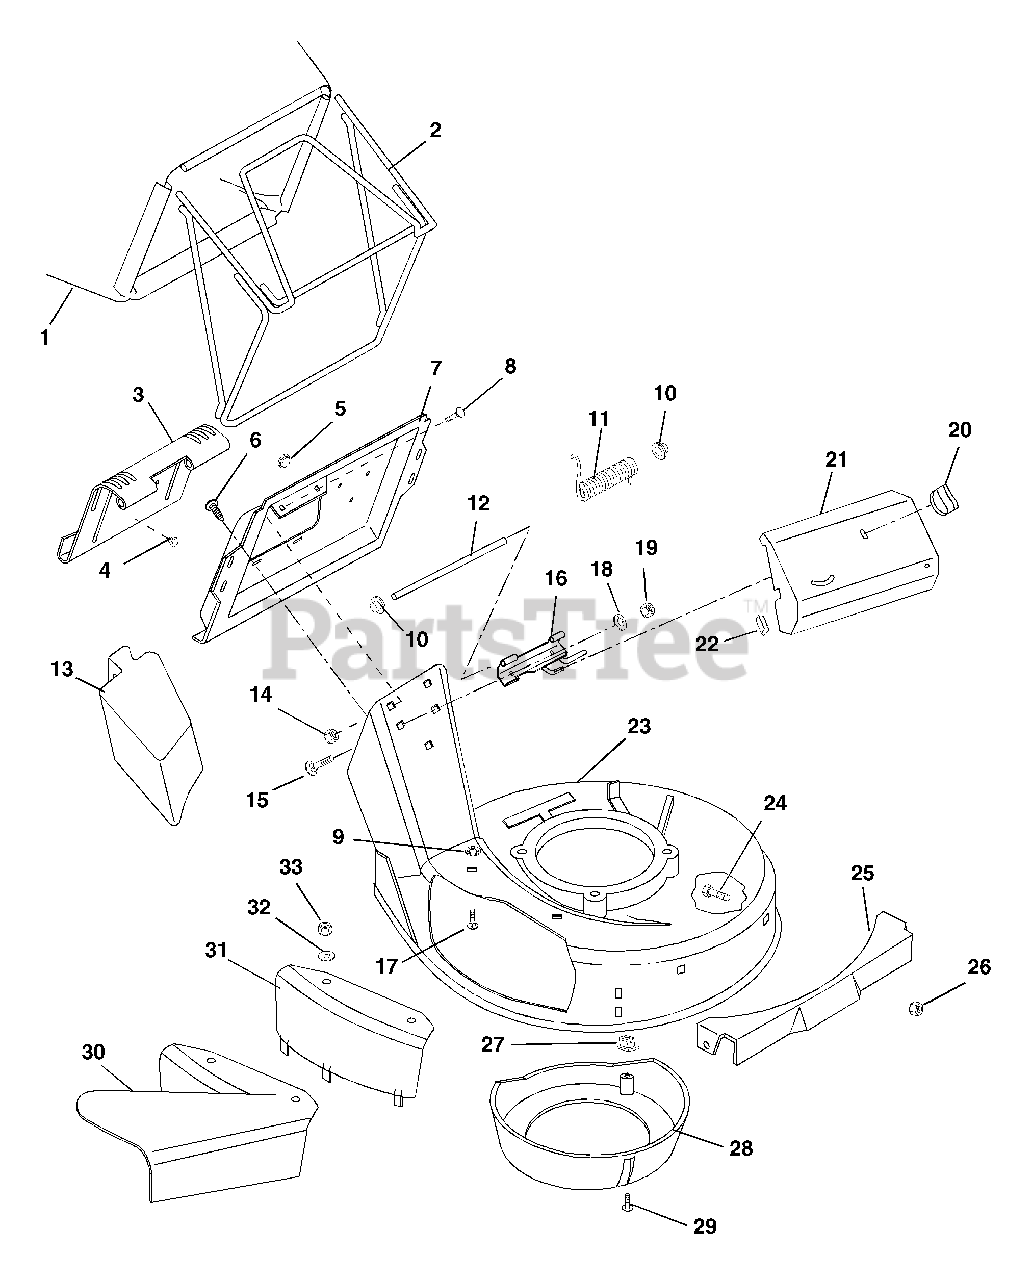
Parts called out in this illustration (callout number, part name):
1	Bag-Consumer Black
2	Bagger Frame
3	Door-Catcher Plate
4	Button Bumper
6	Screw-Tapping 10-24 x .38 Pan Head
7	Plate , Catcher
8	Bolt-Round Head Square Neck .25-20 x .38
9	Nut-Push .312
10	Nut-Push
11	Spring-Torsion .120 x .68 x 3.09
12	Pin-Door
13	Mulch Master Mulcher Accessory
14	Nut-Locking-Flange .25-20
15	Bolt-Round Head Square Neck .25-20 x .75 Grade 5
16	Hinge Base Weldment
17	Bolt-Round Head Square Neck .31-18 x .75 Grade 2
18	Washer-Locking .25 x .077
19	Nut-Hex .25-20
20	Nut-Wing
21	Drive Cover
22	Trim Bumper
23	Mower Pan Head with Decals
24	Bolt-Round Head Square Neck .31-18 x .50 Grade 5
25	Front Panel
26	Nut-Locking-Center .31-18
27	Grommet-Plastic
28	Baffle-Center
29	Screw-Tapping 10-16 x .62 Hex Washer Head
30	Side Discharge Assembly
31	Side Discharge Cover
32	Washer-Flat-Steel .406 x .812 x .065
33	Nut-Locking-Nylon .312-18
